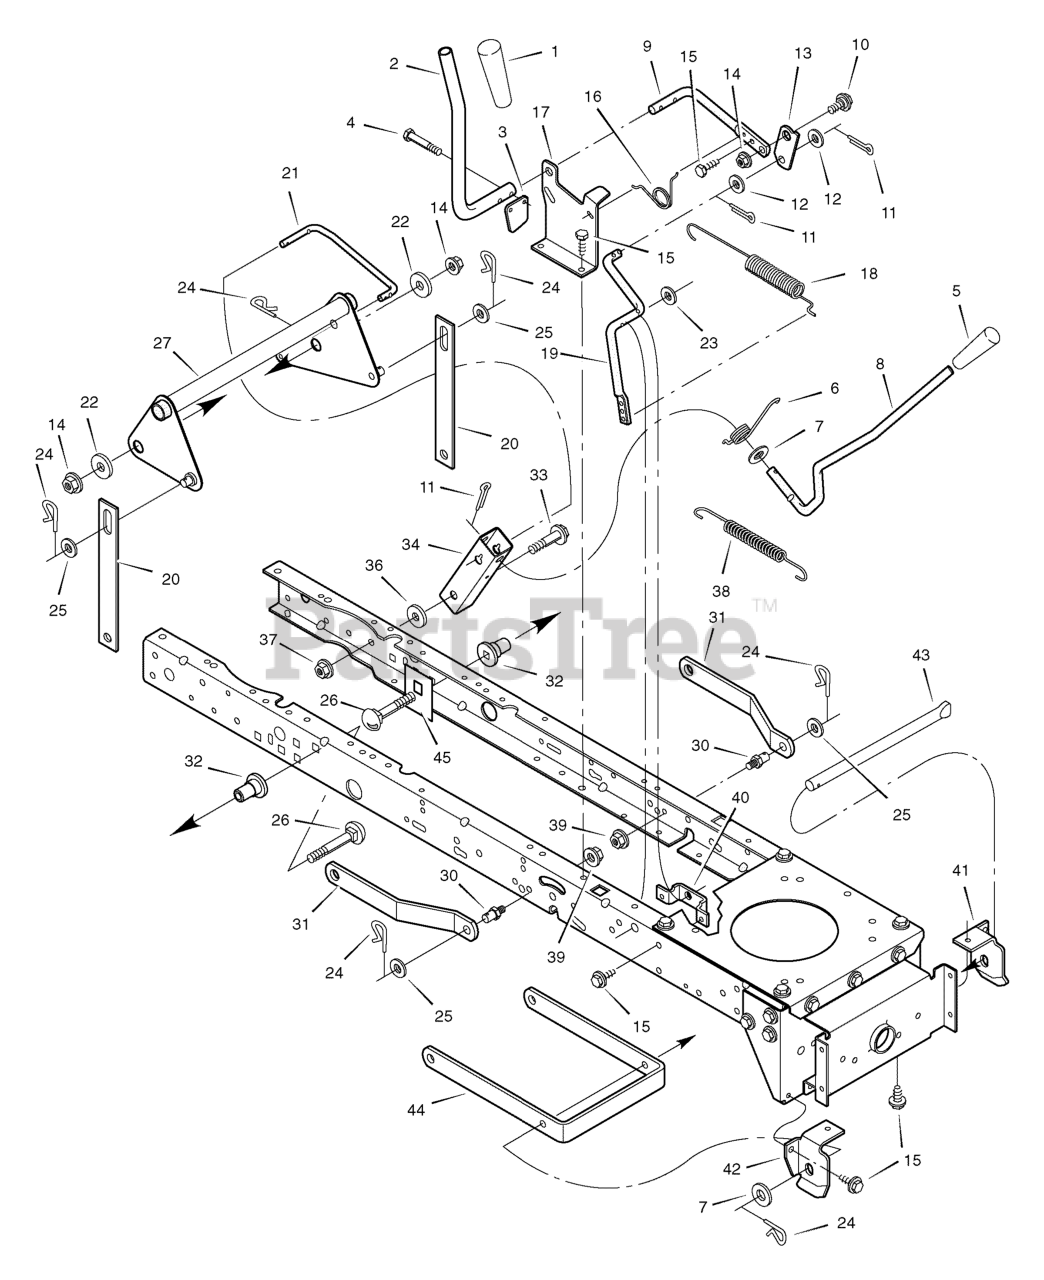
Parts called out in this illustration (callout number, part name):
1	Grip
2	Handle, PTO
3	Pad, Switch
4	Screw, Hex
5	Grip
8	Handle, Lift
9	Lever, PTO
10	Bolt, Shoulder
11	Pin, Cotter
13	Link, PTO
14	Nut, Flange
17	Bracket, PTO
18	Spring, PTO
19	Crank, PTO
20	Link, Lift
21	Link, Lift Handle
24	Pin, Hair
26	Bolt, Carriage
27	Lever Assembly, Lift
30	Pin
31	Bracket, Rear Suspension
32	Spacer, Lifter
33	Bolt, Shoulder
34	Bracket, Pivot
37	Nut, Flange
39	Nut, Flange
40	Bracket, PTO
41	Hanger, Left Deck
42	Hanger, Right Deck
43	Rod, Hanger
44	Bracket, Suspension
45	Plate, Stiffening
